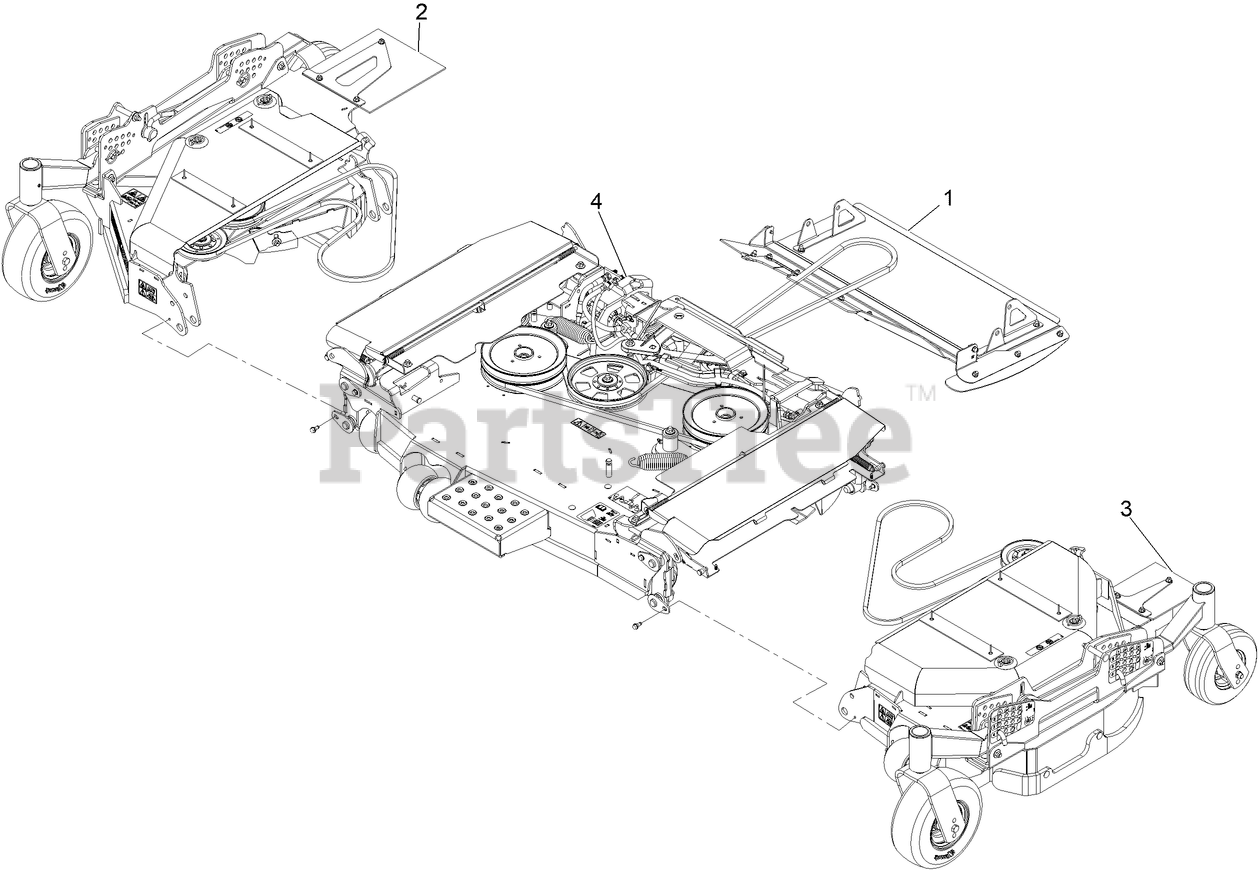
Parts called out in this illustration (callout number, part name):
1	Discharge-Tunnel ASM, 96-Gas
2	ASM-Deck, RH Wing 96
3	ASM-Deck, LH Wing 96
4	ASM-Deck, Ctr 96
